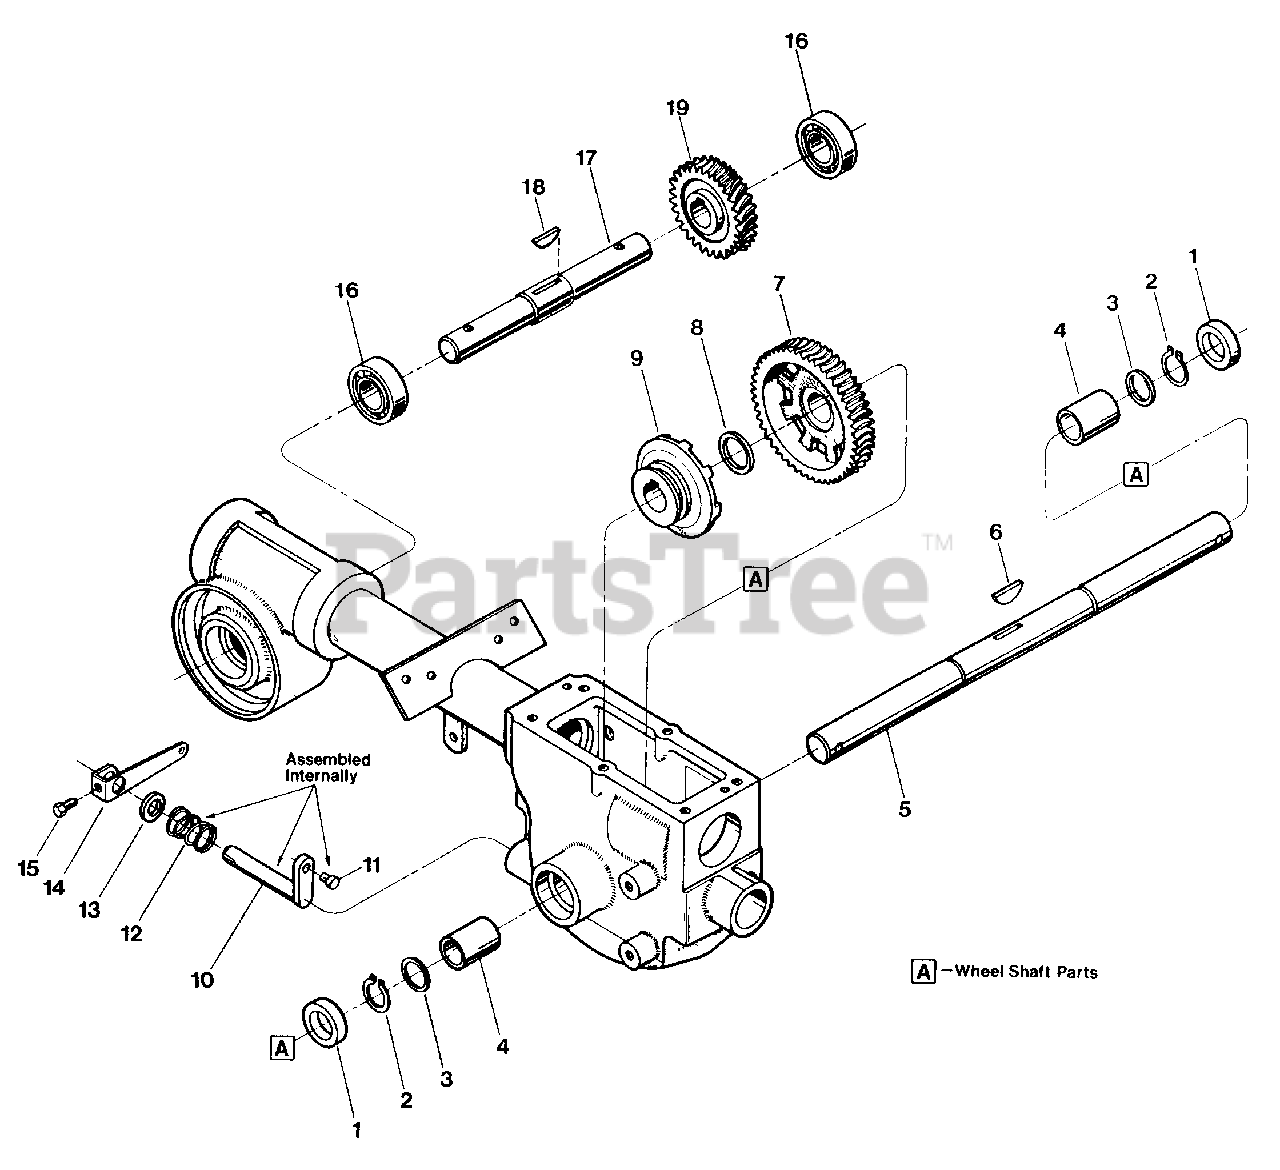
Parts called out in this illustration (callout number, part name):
1	Oil Seal-left and right sides
2	Ring-retaining, heavy-duty, external
3	Shim-1-1/64 I.D., .062 thick
4	Bushing
5	Wheel Shaft (axle)
6	Key-hi-pro (1/4 x 1-5/16), clutch to wheel shaft
7	Gear-wheel drive (worm gear), cast iron
8	Shim-between key and gear
9	Clutch-wheel drive, cast iron
10	Eccentric Shaft-wheel clutch shifting
11	Pin-eccentric shaft
12	Spring
13	Oil Seal-eccentric shaft
14	Lever-eccentric shaft
15	Screw-hex hd, 1/4-20 x 1/2
16	Ball Bearing - for tiller shaft
17	Tiller Shaft
18	Key-woodruff, 1/4 x 1-1/4, for tiller shaft/worm gear
19	Worm Gear-bronze, tiller drive
